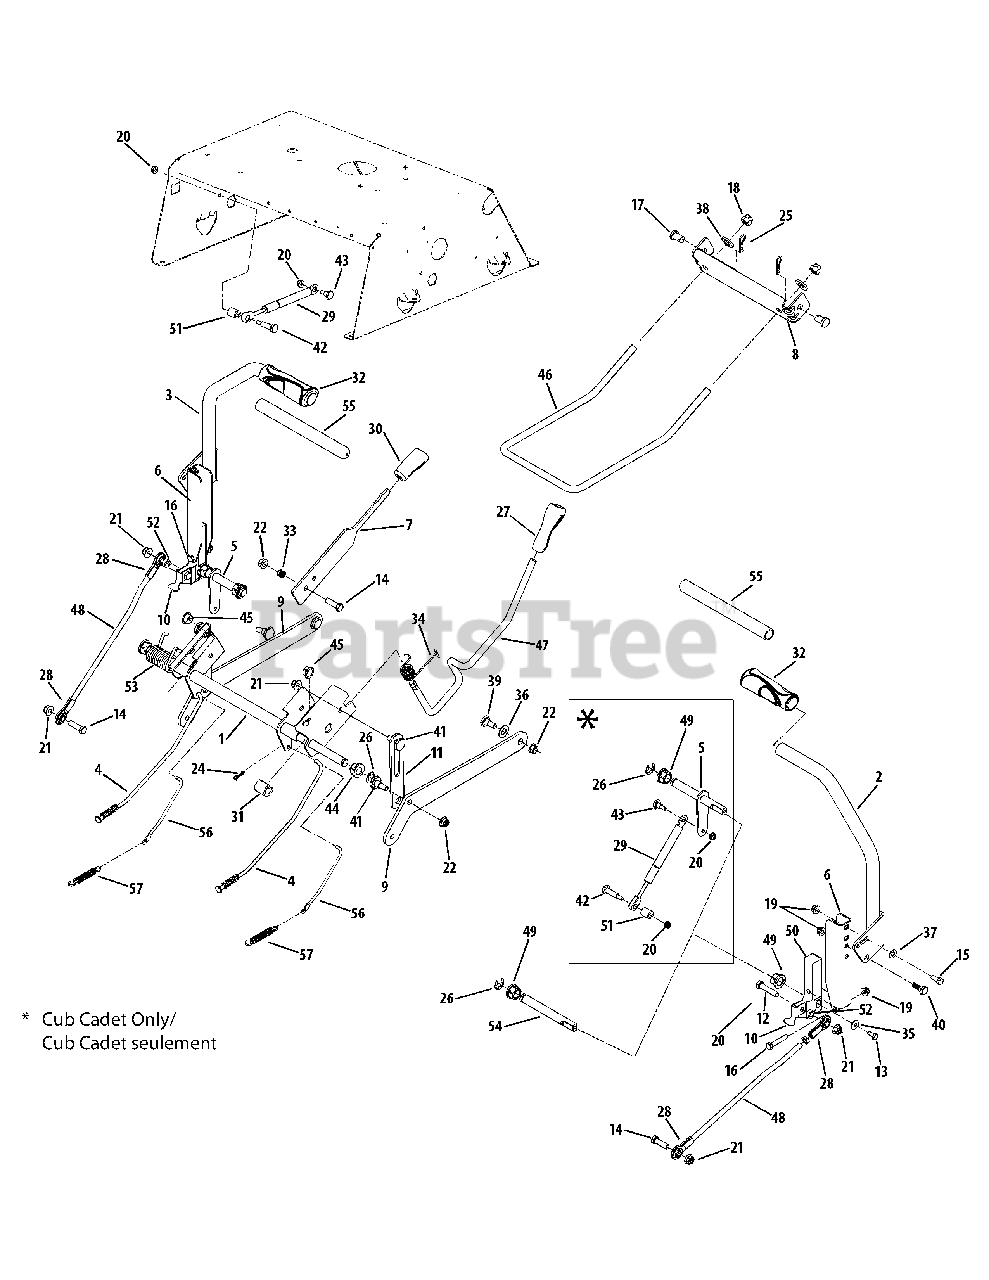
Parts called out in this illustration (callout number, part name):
1	Shaft Assembly, Deck Lift
4	Brake Rod (42" & 50" Decks)
5	Control Shaft
6	Lapbar Pivot Bracket
7	Brake Handle
10	Switch Actuator Bracket
11	Lift Link Plate
12	Hex Screw 3/8-16 x 1.75
13	Hex Bolt 1/4-20 x .625" Lg. Gr. 5
14	Hex Bolt 3/8-16 x 1.25
15	Hex Bolt 5/16-18 x .75" Lg. Gr. 5
16	Hex Screw 5/16-18 x 1.75" Lg.
17	Clevis Pin .50 x .78
18	Hex Flanged L-Nut 1/2-13
19	Hex. Flanged L-Nut 5/16-18 Gr. F, Nylon
20	Hex. Flanged L-Nut Hex 1/4-20 Gr. F Nylon
21	Hex. Flanged L-Nut 3/8-16 Gr. F Nylon
22	Hex. Flanged L-Nut 3/8-16 Gr. F
23	Jam Nut 3/8-24
24	Bow Tie Cotter Pin
25	Cotter Pin
26	E-ring
27	Handle Grip
28	Rod End
29	Cylinder, Damper
30	Handle Grip
31	Spacer .62 x 1.0
32	Hand Grip
33	Compression Spring
34	Spring, Torsion RZT
35	Cupped Washer .265 ID x .75 OD x .062
36	Flat Washer .53 ID x 1.00 OD x .06
37	Flat Washer .34 ID x .688 OD x .065
38	Flat Washer .531 ID x 1.0 OD
39	Shoulder Screw .500 Dia. x .335" Lg.
40	Shoulder Screw
41	Shoulder Screw .50 Dia.
42	Shoulder Screw .375 x 1.16
43	Shoulder Screw .375 x .38:1/4-20
44	Hex Flange Bearing .630 ID
45	Flange Bearing .626 x .938 x .344
46	Deck Front Hanger Rod
47	Deck Lift Handle Rod
48	Lapbar Control Rod
49	Hex Flange Bearing
50	Control Hub
51	Spacer, .385 x .63 x .75
52	Spacer, .380 x .625 x .265
53	Torsion Spring (50" Deck Only)
54	Control Shaft (42" Deck)
54	Control Shaft (50" Deck)
55	Grip (Lampbar)
56	Brake Rod (54" Deck)
57	Ext. Spring .59 x 4.0" Lg. (54" Deck)
